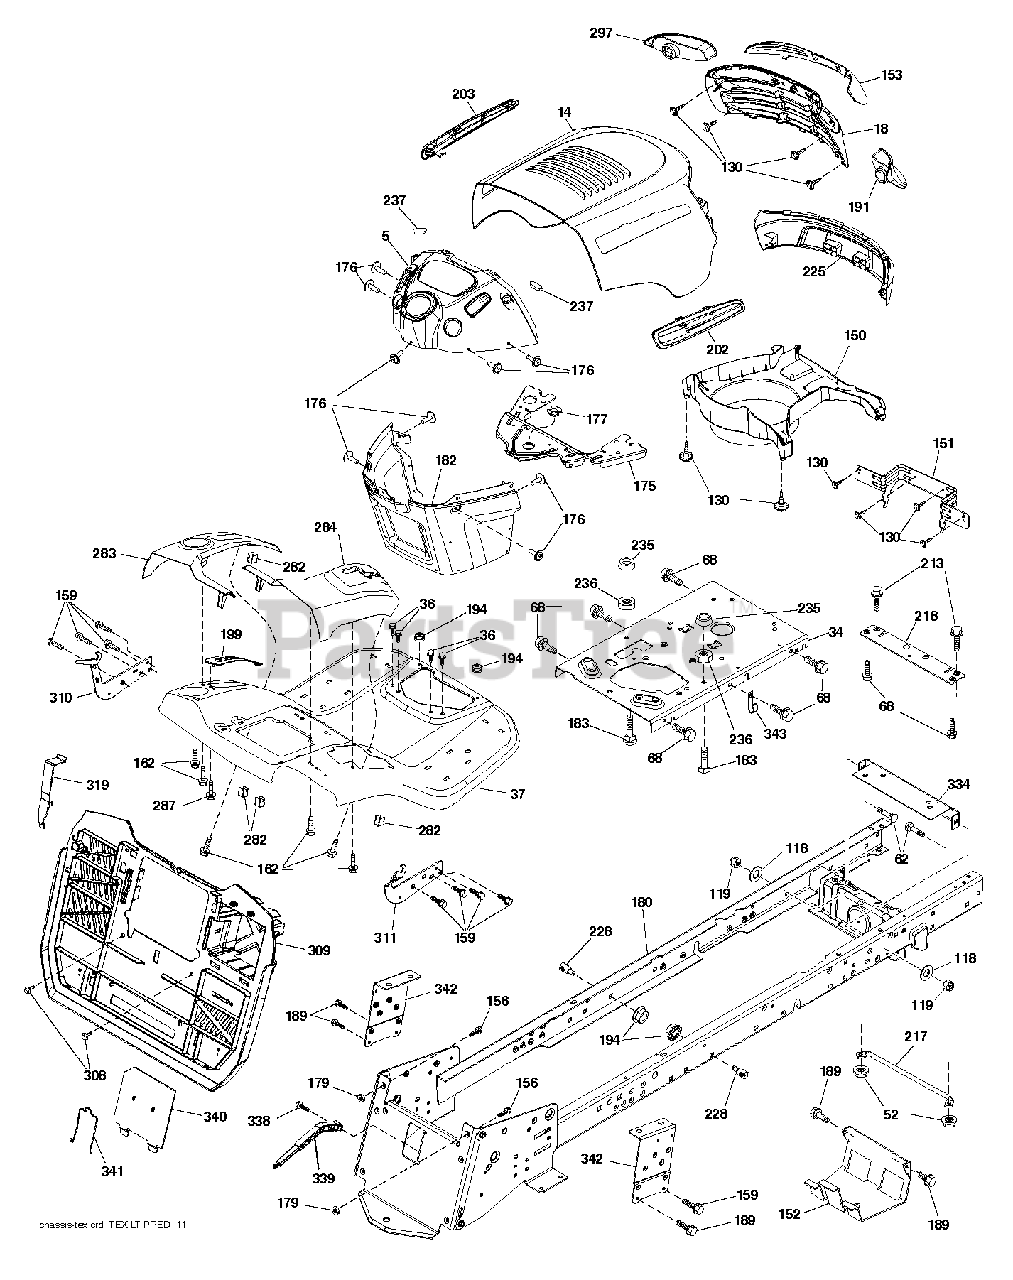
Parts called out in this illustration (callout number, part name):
5	DASH.PREDLT.CC.ICY.CK.N/SRV.BL
14	HOOD.PNT.PREDATOR.LT.TX.667
18	GRILLE.SVC.BASE.PREDATOR.LT428
34	PLATE .ENGINE.127".10GA.
36	SCREW 5/16"
37	FENDER.TEX.SRD.CRD.BASE
52	LOCKNUT
119	LOCKNUT
130	SCREW.#10 X 0.750.BOS THREAD
150	DUCT.AIR.PREDATOR.LT.2.36"
151	BRACKET.PIVOT.ALPHA.LT
152	SHIELD BROWNING
153	LENS.PREDATOR.LT
156	BOLT
159	SCREW, 3/8-16X3/4
162	SCREW.HI-LO.CONSOLE
176	SCREW.#10-24X5/8.RN.QU
177	BUSHING STEERING
182	DASH.LWER.PREDATOR/HUSQ.LT
183	BOLT.5/16-18X1-1/4 FULL THD
189	SCREW
191	INSERT.REFLECT.PREDATOR.LT.RH
194	NUT LOCK HEX FLANGE 5/16-18
203	VENT.SIDE.PRED.LT.LH.JONSERED
213	BOLT
217	ROD.PIVOT.HOOD
218	X-PIECE.HOOD.STOP.NON/
225	BUMPER.GRILLE.PRED.LT.JONS.505
228	STUD.FASTNER.W/ANTI-ROTATE
235	SPACER FENDER
236	NUT.CENTERLOCK.5/16-
237	PLUG.MOUNT.CARGO.BLK
282	CLIP.RETAINER.CONSOLE.LT.HUSQ
283	CONSOLE.DECKLIFT.LH.SRD.TEXCRD
284	CONSOLE.SHIFT.HYDRO.TEX.CRD
297	REFLECTOR.INSERT.PRED.LH.LT
308	BOLT, 5/16-18 X 1 3/4
310	LH.ADJUST.HANGER.BRACKET.ASM
311	RH.ADJUST.HANGER.BRACKET.ASM
319	BRACKET.ACTUATOR.BAGGER.SRD
334	Engine Bracket
338	BOLT BOLT SHOULDER
339	LEVER LEVER BAGGER
340	DOOR.PNT.BATTERY.TRY.TEX.CRD.
341	LATCH
342	SUPPORT SUPPORT FENDE
343	Clip
